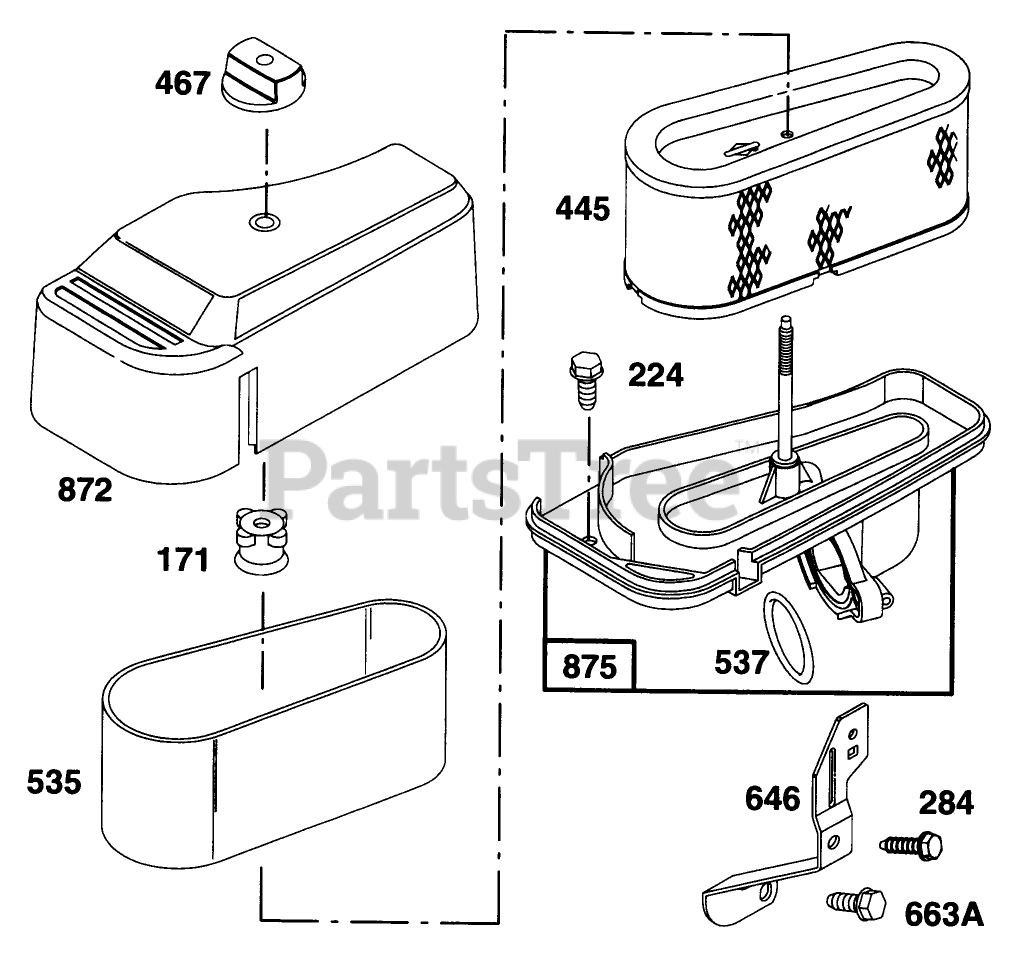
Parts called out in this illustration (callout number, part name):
224	Screw-Sem
284	Screw
445	Filter-Air
535	Filter-Air
537	O-Ring
646	Brace-Air Cleaner
663A	Screw
872	Cover-Air Cleaner
875	Body-Air Cleaner
